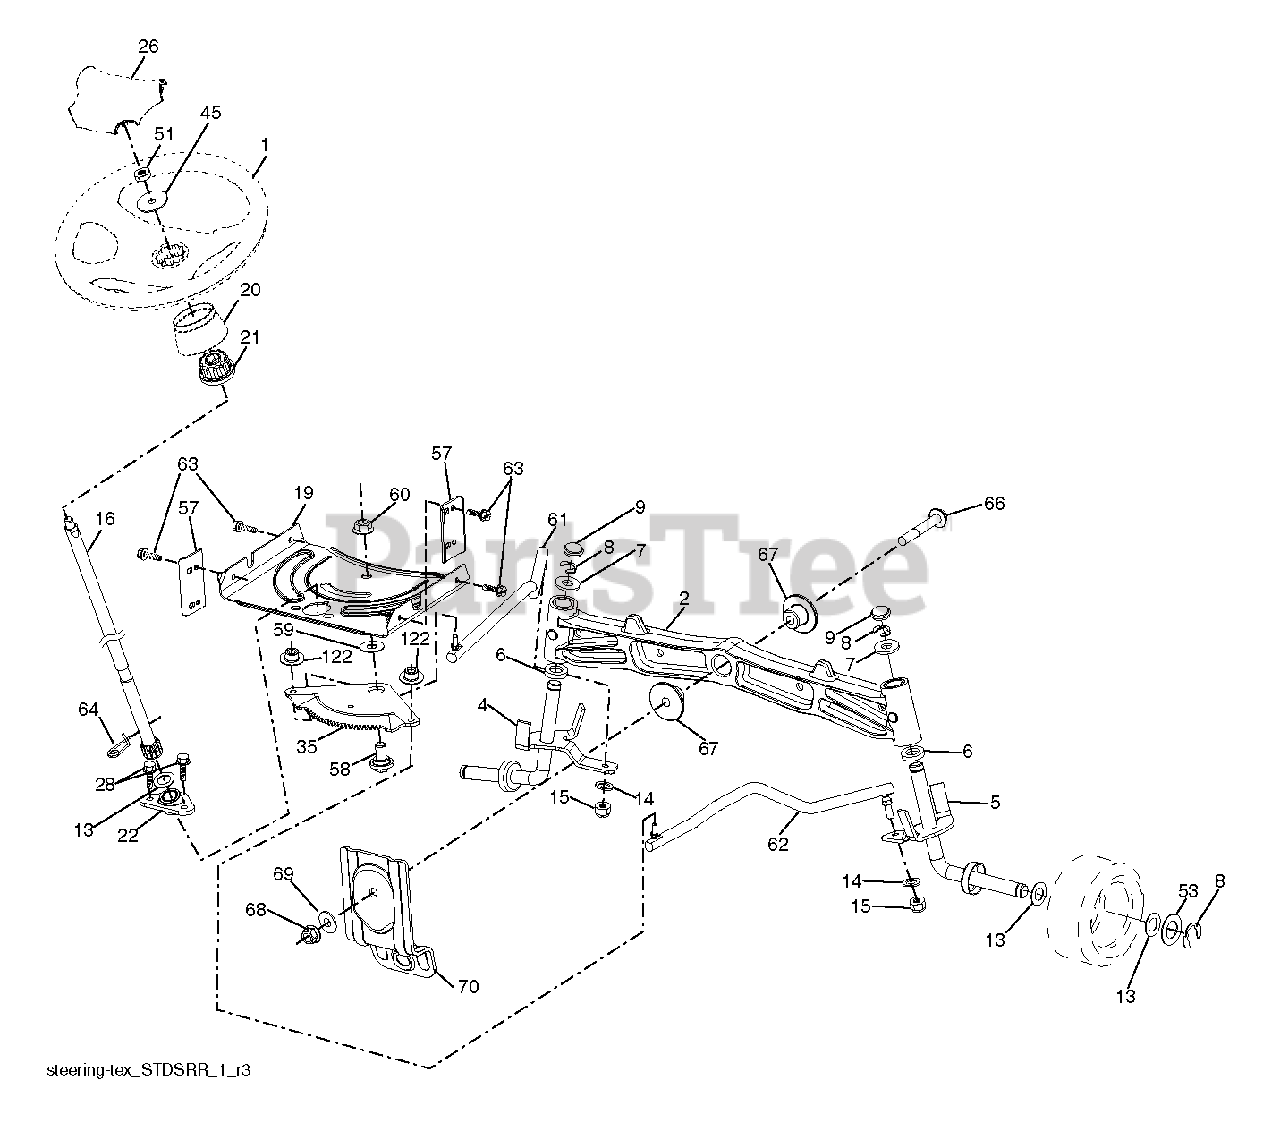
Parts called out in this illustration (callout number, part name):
1	WHEEL, STEERING
4	SPINDLE.WELDED.LH.15"T
5	SPINDLE.WELDED.RH.15"T
6	BRNG T
14	WASHER, LOCK 3/8
15	NUT CROWNLOCK 3/8-24
19	PLATE.STEER.DDL.NLT/NG
20	BOOT.STEERING.
21	ADAPTER, WHEEL STNG
22	STEERING.SUPT.LOWER.
26	INSERT, WHEEL STEERING
28	SCREW, 3/8-16X3/4
35	GEAR.SECTOR.PLATE.DDL.
58	BOLT.SHOULDER.SECTOR.P
59	WASHER.THURST.SECTOR.S
60	NUT FLANGE LOCK 5/8-11
61	DRAGLINK.LH.BALLSTUD.D
62	DRAGLINK.RH.BALLSTUD.D
63	SCREW
64	RETAINER.CLIP.SPRING.S
66	BOLT HEX FGHD 7/16-14 X 3 SERR
67	BUSHING.PM.FRONT AXLE
68	NUT.LOCK.FLANGE.7/16
69	WASHER.1.5X.505X.118
70	BRKT.DECK.SUSPENSION.F
